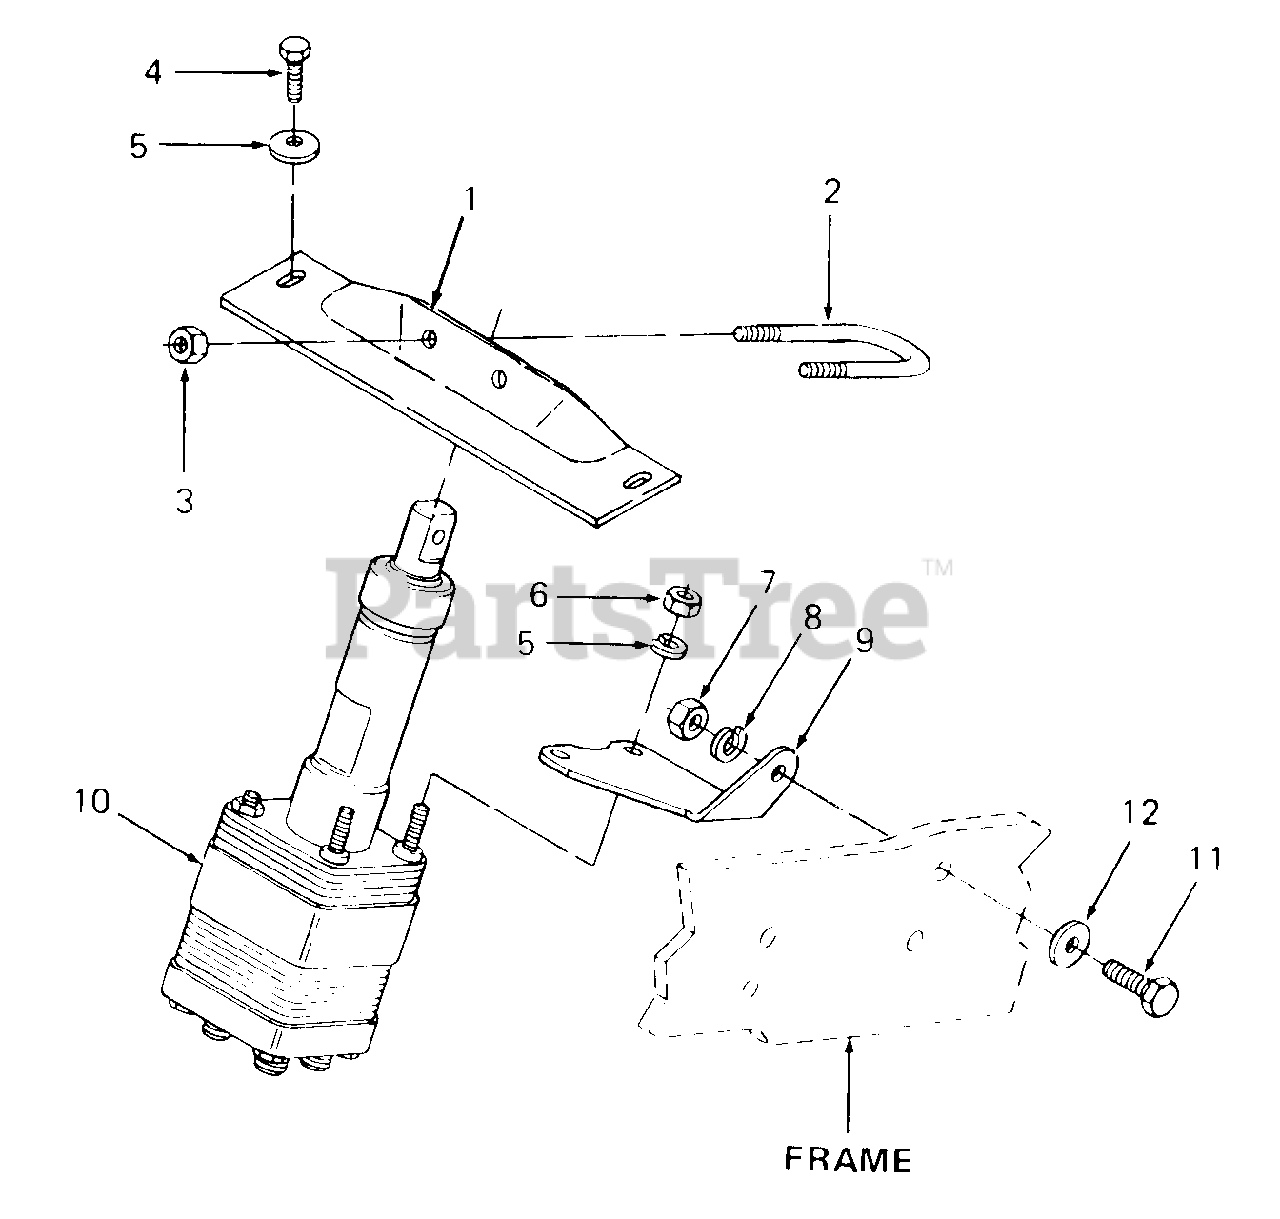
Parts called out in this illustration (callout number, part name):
1	Plate, Steering Support
3	Nut, Hex Center Lock, 5/16-24
4	Screw, Hex Cutting, 5/16-1 8 X .75 Lg
5	Washer, Bell, .345 X .88 X.060 Thk
6	Nut, Hex, 5/16-24 GR5
7	Nut, Hex Center Lock, 3/8-16 GR5
8	Washer, Lock, 3/8
9	Bracket, Power Steering Box Mtg
10	Power Steering Box w/Flat
11	Screw, Hex Cap, 3/8-16 X.75 Lg GR5
12	Washer, Flat, .385 X.87 X .06 Thk HDN
